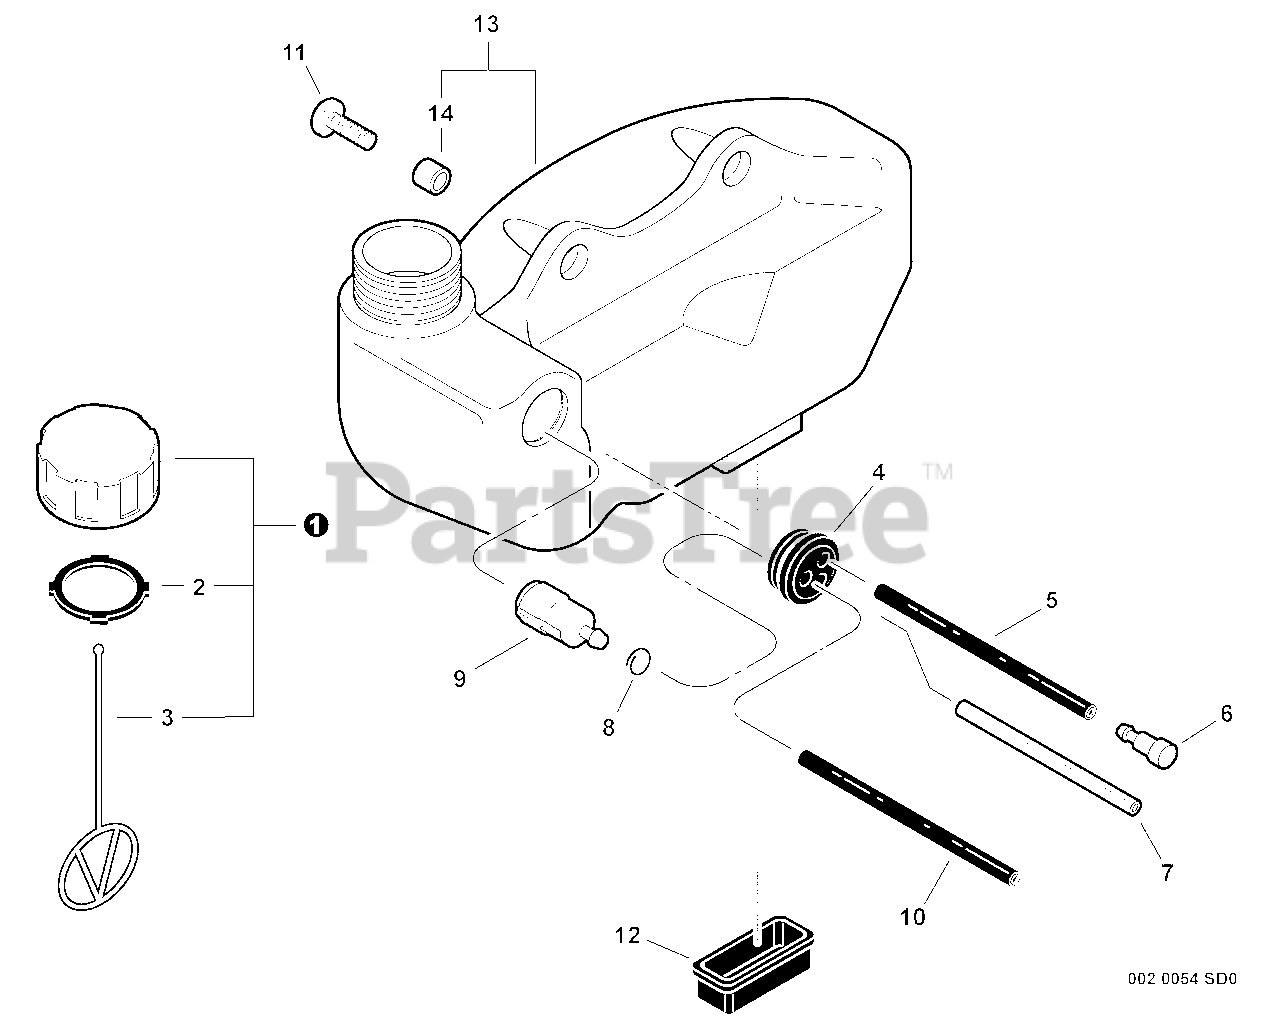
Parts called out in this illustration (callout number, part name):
1	CAP ASSY - RED
2	GASKET, CAP
3	CONNECTOR, CAP
4	GROMMET
5	PIPE - 3X5X70 -- BLACK
6	VENT, FUEL TANK
7	PIPE - 3X6X110 -- CLEAR
8	CLIP - 6
9	FILTER, FUEL
10	PIPE - 3X5X195 -- BLACK
11	SCREW - 5X15
12	CUSHION, FUEL TANK
13	FUEL TANK ASSY
